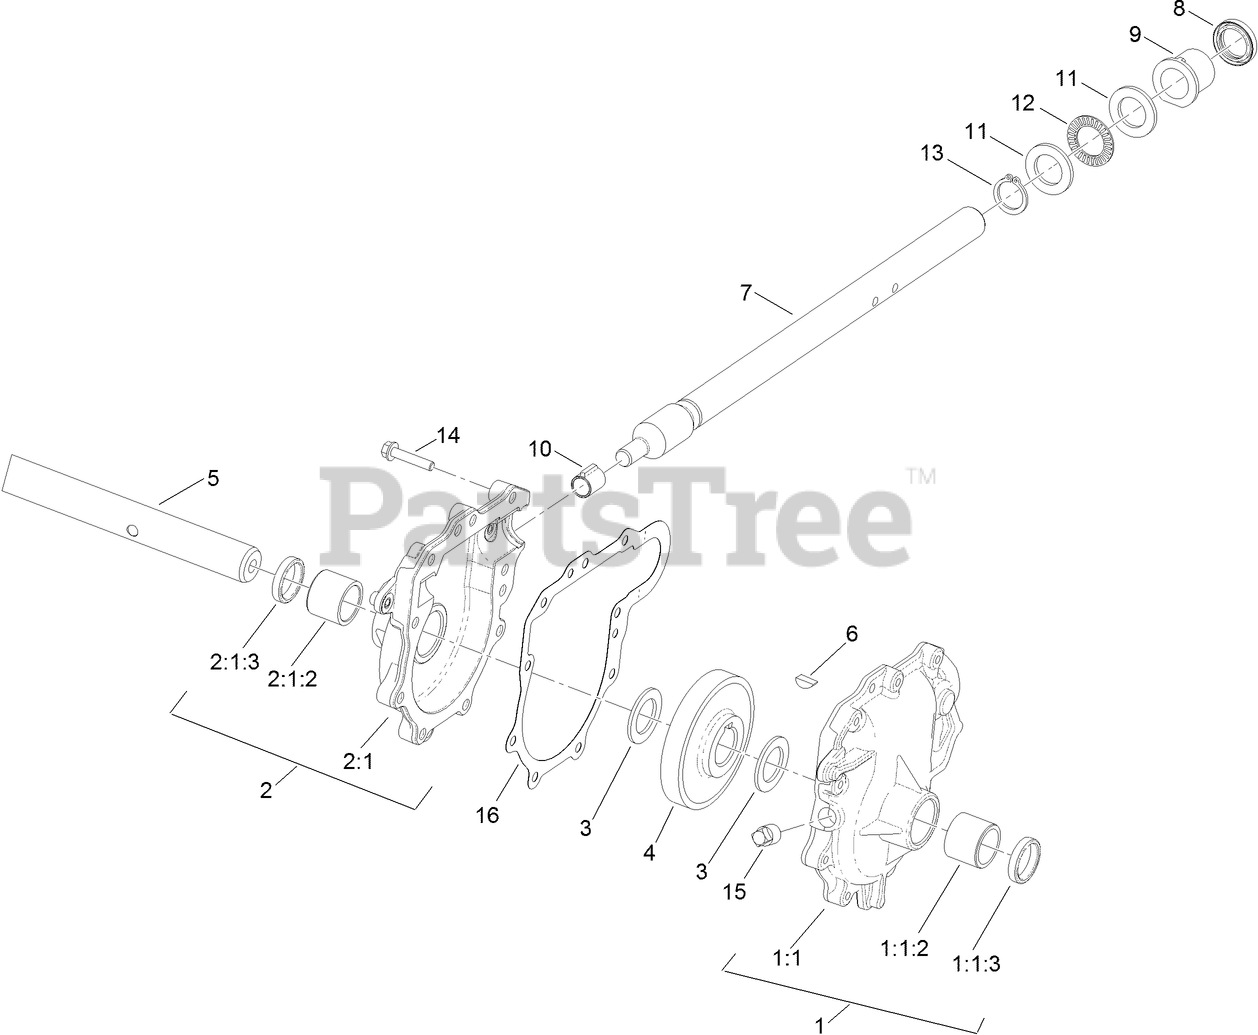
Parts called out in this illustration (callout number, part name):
1	LH AUGER GEARCASE ASM
1:1	Gearcase-Auger, LH
1:1:2	BUSHING-SLEEVE
1:1:3	SEAL-OIL
2	RH AUGER GEARCASE ASM
2:1	Loose Parts Package
2:1:2	BUSHING-SLEEVE
2:1:3	SEAL-OIL
3	WASHER-THRUST
4	GEAR-HELICAL
5	SHAFT-AUGER
6	KEY-WOODRUFF
7	SHAFT-IMPELLER
8	SEAL-OIL
9	BUSHING-INPUT
10	BUSHING-WORM
11	WASHER-THRUST
12	BEARING-THRUST
13	RING-RETAINING, EXT
14	SCREW-HWHTF
15	PLUG-PIPE, SQH
16	GASKET-GEARCASE, AUGER
